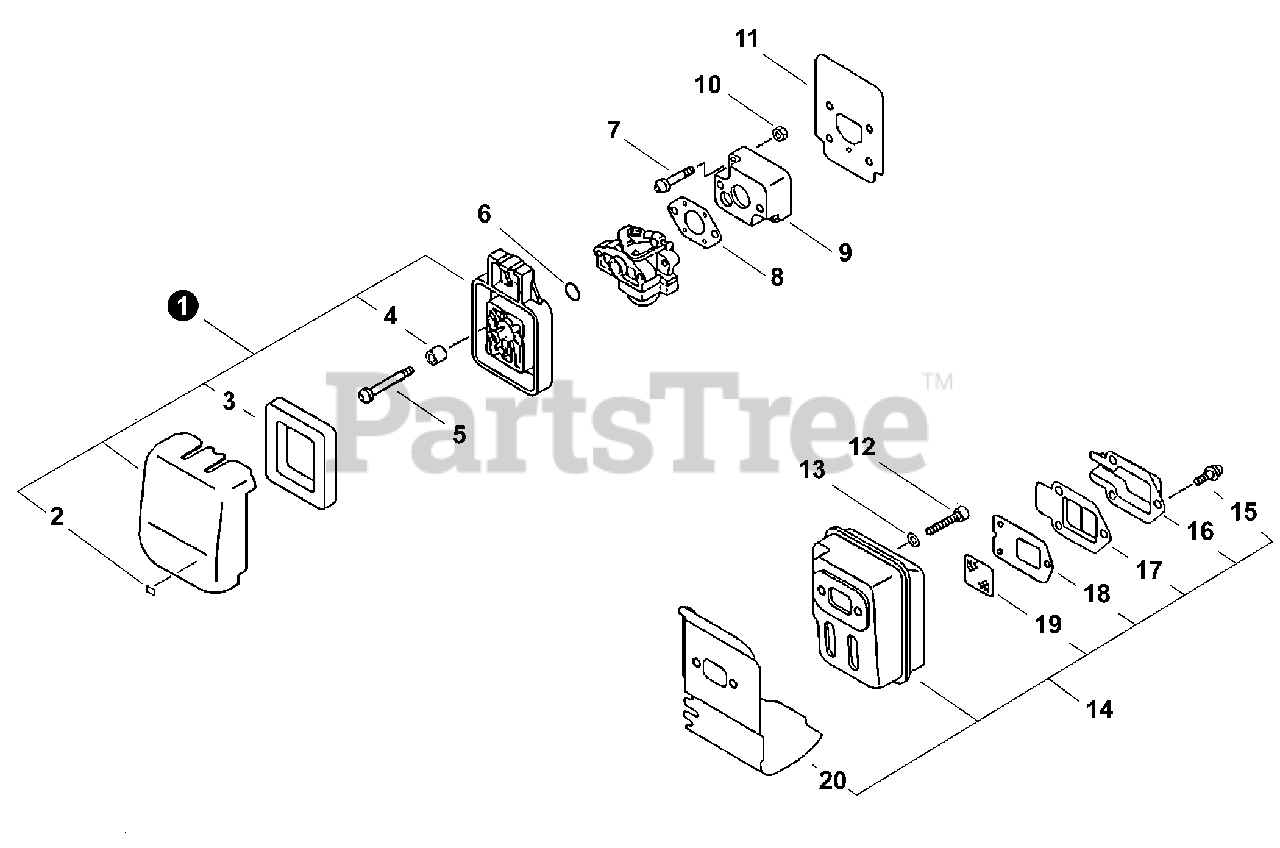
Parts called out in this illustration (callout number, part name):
1	AIR CLEANER ASY
3	FILTER, AIR
4	SLEEVE
5	SCREW - 5×64
6	O-RING - 15
7	SCREW - 5×22
8	GASKET, INTAKE
9	INSULATOR, INTAKE
11	SHIELD, INTAKE
12	SCREW - 5×55
13	WASHER - 5
14	MUFFLER ASY
15	SCREW - 4×10
16	GUIDE, EXHAUST - OUTER
17	GUIDE, EXHAUST - INNER
18	GASKET, EXHAUST
19	SCREEN, SPARK ARRESTER
20	GASKET, EXHAUST
